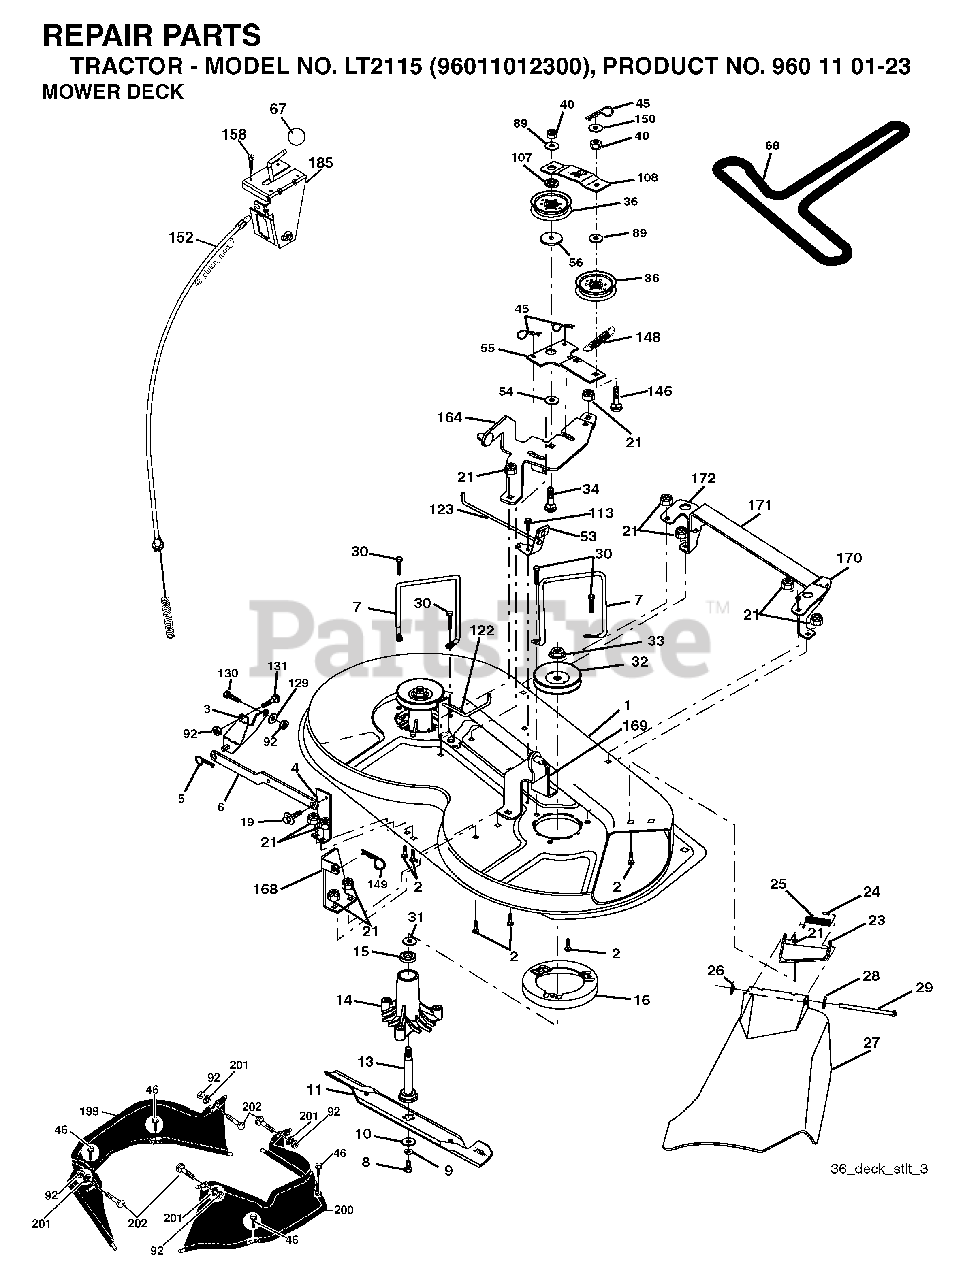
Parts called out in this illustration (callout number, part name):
1	DECK.WELDMENT.38"2005
2	BOLT
3	BRKT ASM SWAY BAR
4	BRACKET DECK SWAY BAR 38"/42"
5	RETAINER-SPRNG RB
6	BAR SWAY DECK
7	NUT.71038.31-18.HEX.NYLOCK
8	BOLT.WASHER.ASM.7/16-2
11	BLADE 38" PREMIUM
13	SHAFT.ASM.MDRL.N/GREASE.38
14	HOUSING MANDREL
18	BOLT
19	BOLT SHD 5/16-18
20	BAFFLE VORTEX
21	LOCKNUT
23	BRKT.DEFLECTOR.38"2005+
24	CAP-SLEEVE LT
25	SPRING.TORSION.DEFLECT
26	NUT PUSH M
29	ROD.HINGE
30	SCREW, WASHER HEAD
31	WASHER.SPACER.MANDREL
32	PULLEY MANDREL
33	NUT.FLANGE.LOCK.TOP
36	FLAT IDLER PULLEY
37	PULLEY.IDLER.FLAT.UNPLATED
40	LOCKNUT
45	RETAINER M
46	SCREW.1/4-20X5/8
55	IDLER ARM
56	SPACER.RETAINER.MOWER
67	KNOB T (3/8 HOLE)
68	V-BELT.MOWER.38"2005+
72	SPRING.BRAKE.RETURN.38"
89	WASHER
92	NUT
107	SPACER.IDLER.ARM
108	STIFFENER.IDLER.ARM
129	WASHER
131	BOLT D
144	KEEPER BELT
148	IDLER RETURN SPRING
149	SPRING.RETAINER.YELLOW.ZINC
150	WASHER LT
152	CABLE.CLUTCH.38".SERVICE
158	SCREW
185	HEAD ASM. CABLE CLUTCH
186	SCREW.HXWSH.3/8
187	KEEPER BELT
188	BOLT, CARRIAGE IDLER
189	STAND, BRAKE
190	ARM, BRAKE
191	SPACER, BRAKE
192	BOLT/WASHER ASM 5/16-18
193	KEEPER BELT RH MANDREL
194	GUARD BRAKE
195	WASHER 12/32X2X10GA
198	SCREW, 5/16-18 X 1/2
201	PUSH.NUT.ROUND.3/8.DIAM
